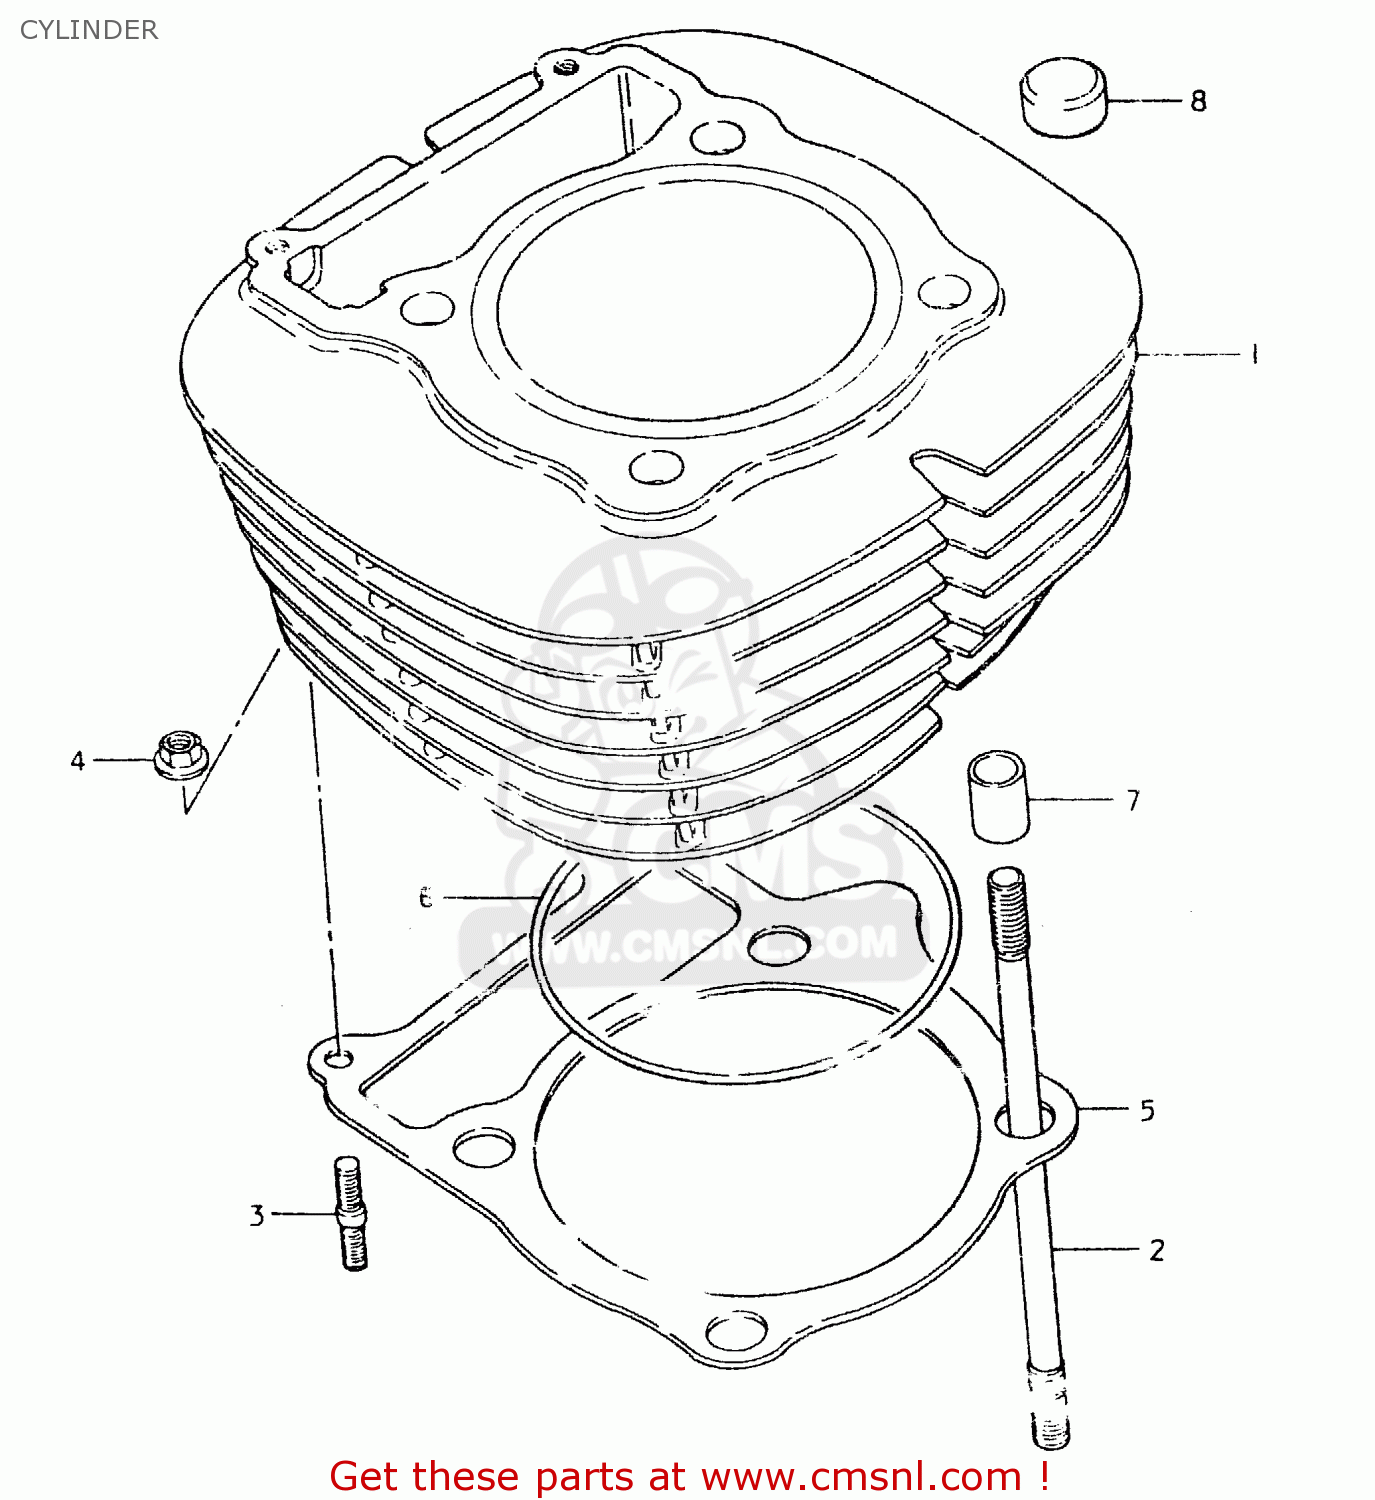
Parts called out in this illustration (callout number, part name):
1	CYLINDER
2	STUD
3	STUD 6X20
4	NUT
5	GASKET,CYLINDER (MCA)
6	O RING(D:2,ID:87)
7	PIN
8	PAD,CYLINDER HEAD
